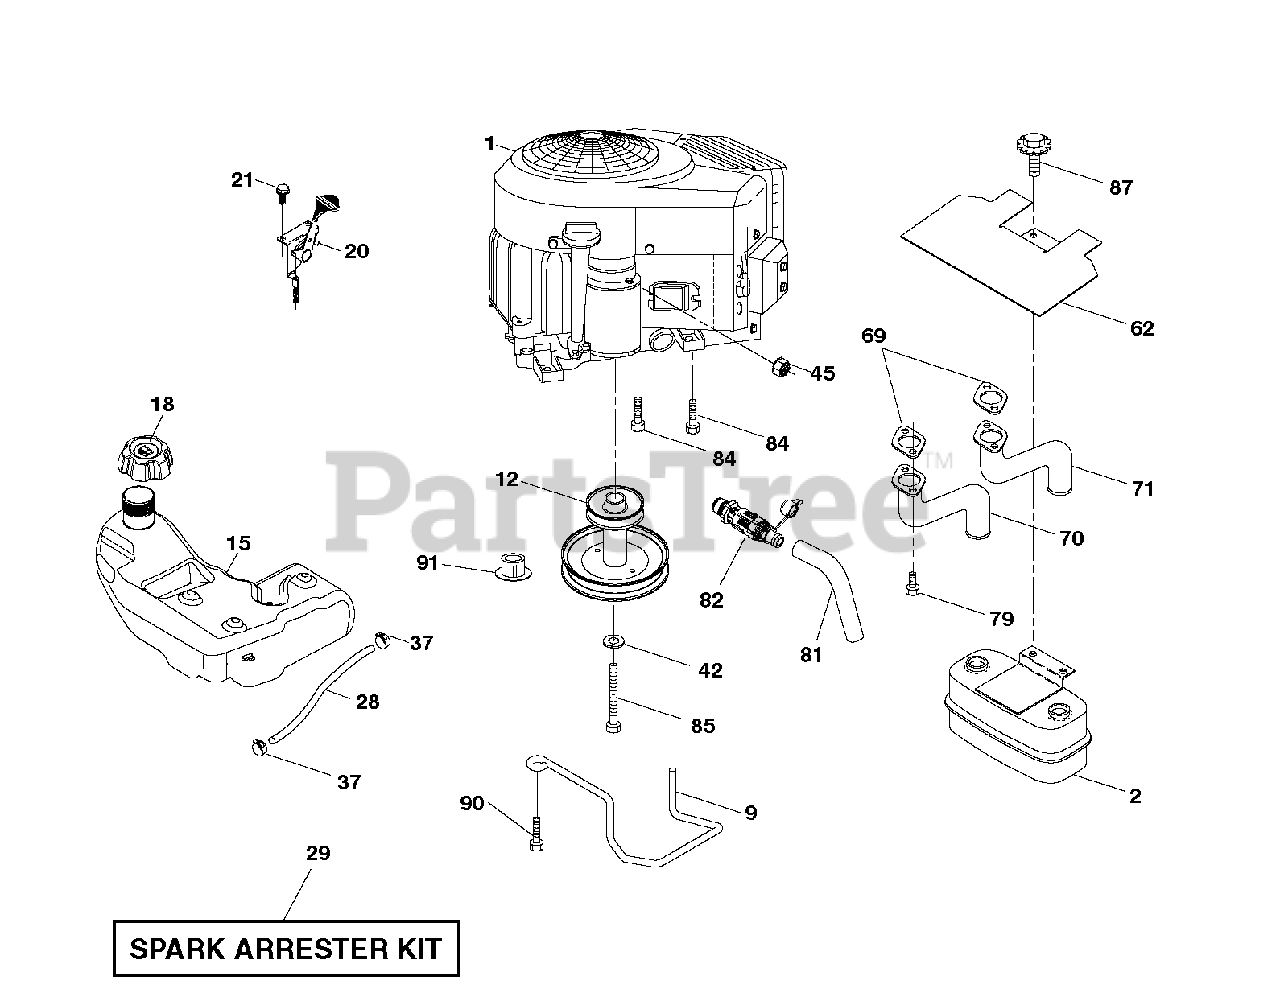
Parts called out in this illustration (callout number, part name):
2	MUFFLER.TWIN.CYL.LOW.TONE
9	KEEPER.BELT.ENGINE.4.2
12	PULLY ENGINE
15	TANK.ASSY.3.GAL.EPA
18	CAP ASM.FL.RTCHT.3"GRY.E10
20	CONTROL.TH/CK.COBRA.B&S.TWN.
21	SCREW.#10 X 0.750.BOS THREAD
29	ARRESTER SPARK (OPTIONAL)
37	HOSE CLAMP
42	LOCKWASHER
45	NUT
62	SHIELD.HEAT.MUFFLER
69	GASKET.MUFFLER
70	TUBE MANIFOLD LH
71	EXHAUST TUBE RH
79	SCREW.SOCKET.HEAD.5/16-18
81	TUBE, DRAIN OIL ASM.
82	VALUE.OIL.DRAIN
84	SCREW.3/8-16
85	BOLT HEX 7/16-20X4-1/4"
87	BOLT, 5/16-18 X 1 3/4
90	SCREW 3/8-16X1
91	BUSHING.1.375OD
